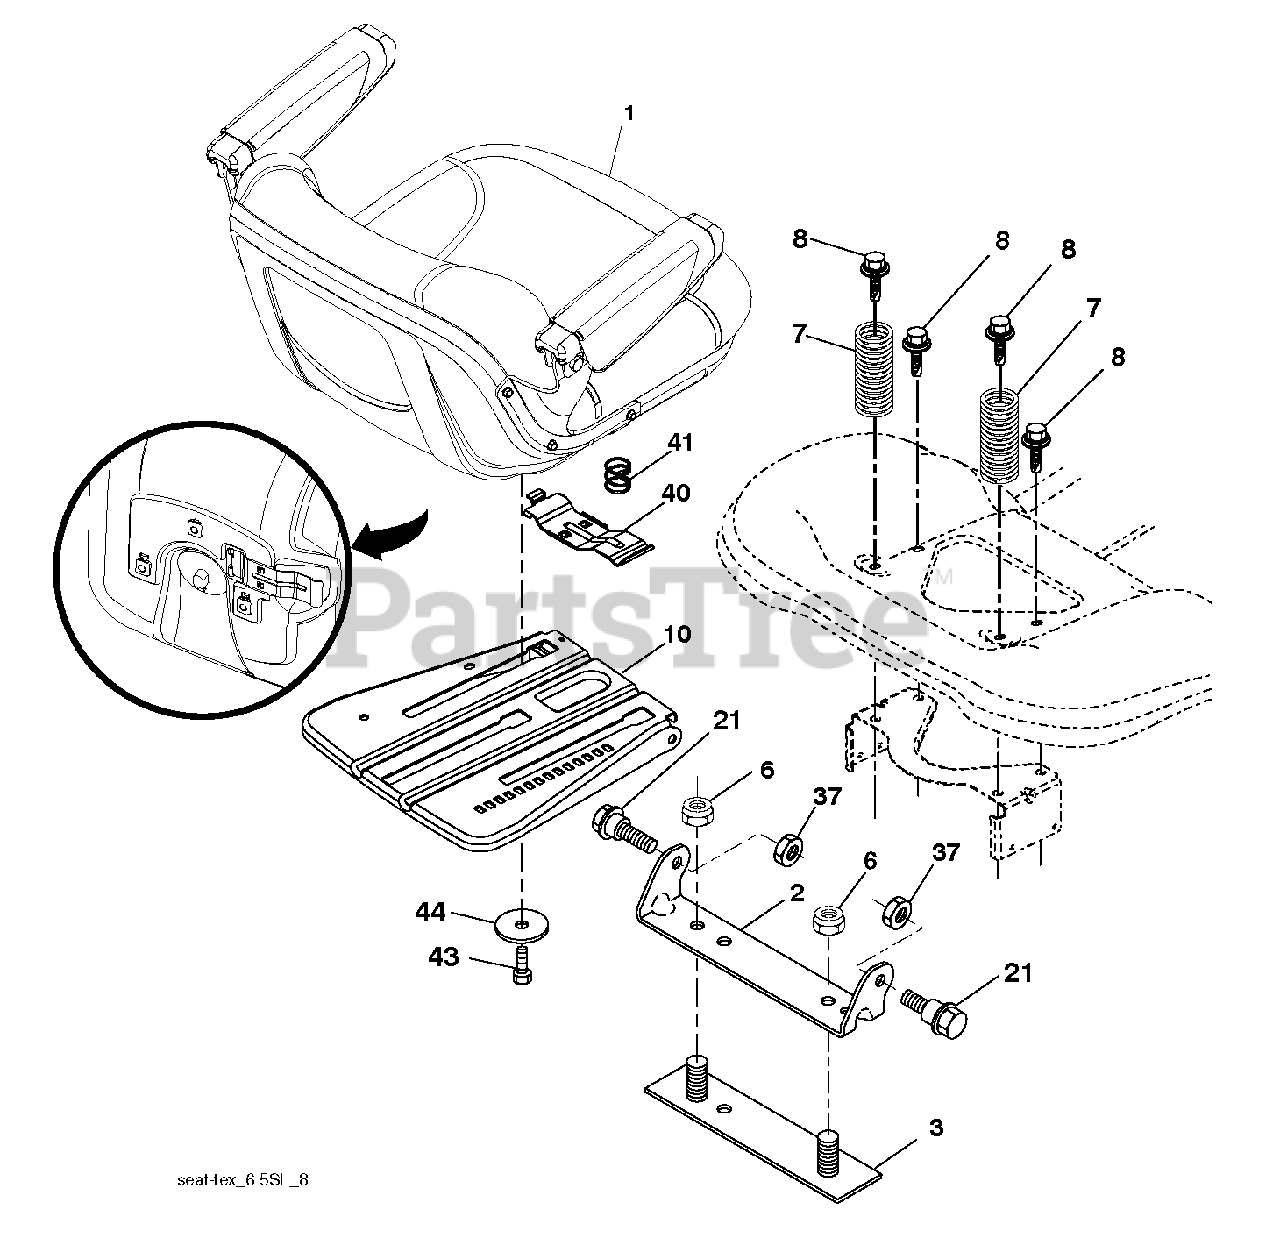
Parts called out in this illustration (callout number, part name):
1	SEAT.TH154.GREY.HUS.ARMREST
2	BRKT.PIVOT.FENDER
3	STRAP
6	NUT
7	SPRING COMPRESSION
8	BOLT, 5/16-18 X 1 3/4
10	PAN.ASM.SEAT.3PT
21	BOLT.SHOULDER.5/16-18
37	NUT.71038.31-18.HEX.NYLOCK
40	HANDLE.SLIDE.SEAT.TEX.GREY
41	SPRING.LATCH.SEAT.TEX
44	WASHER 13/32 X 2-3/8 X 12GA
